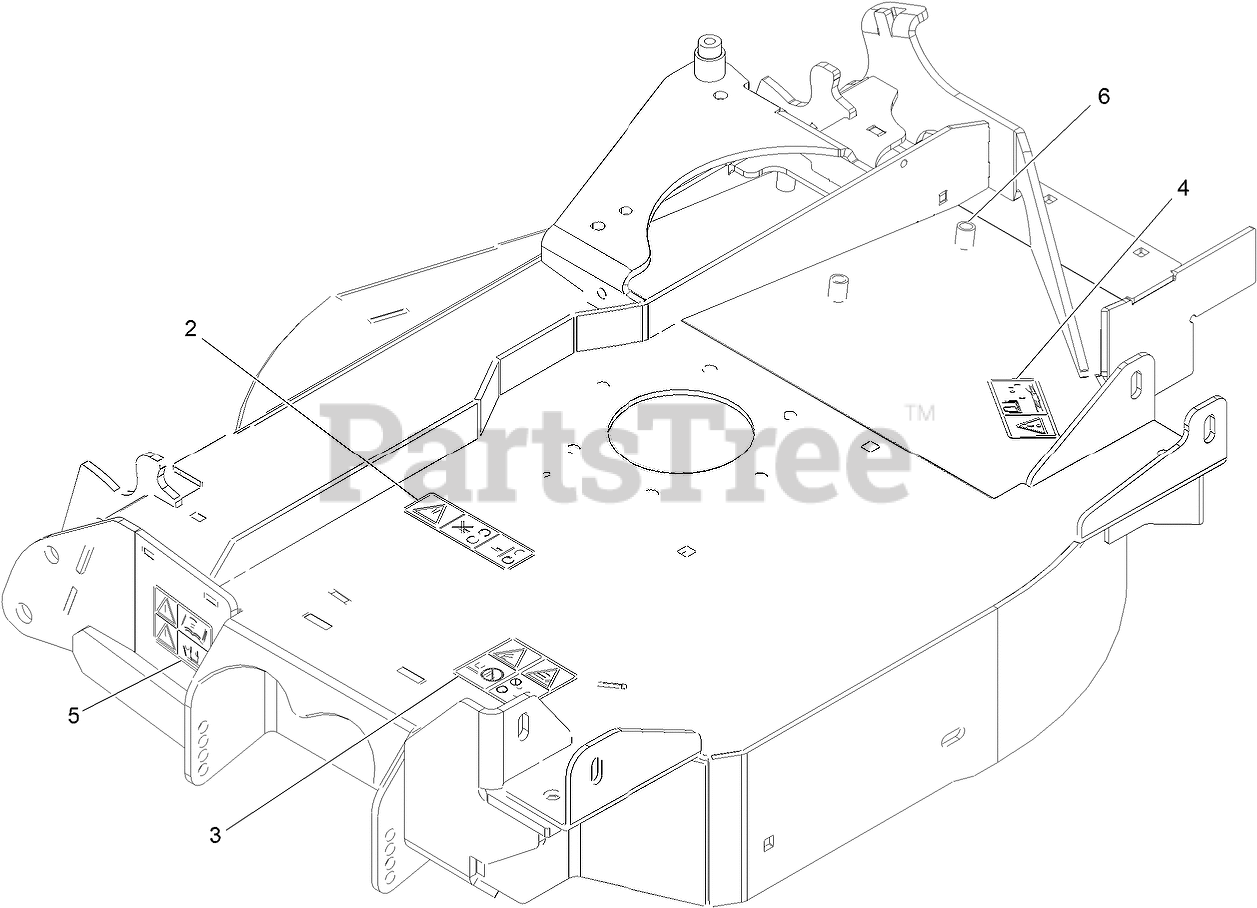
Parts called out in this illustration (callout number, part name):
2	DECAL-COVER, MISSING
3	DECAL-DANGER, THROWN OBJECT
4	DECAL-BOLT TORQUE
5	DECAL-WARNING, PINCH POIN
6	NUT-CLINCH
